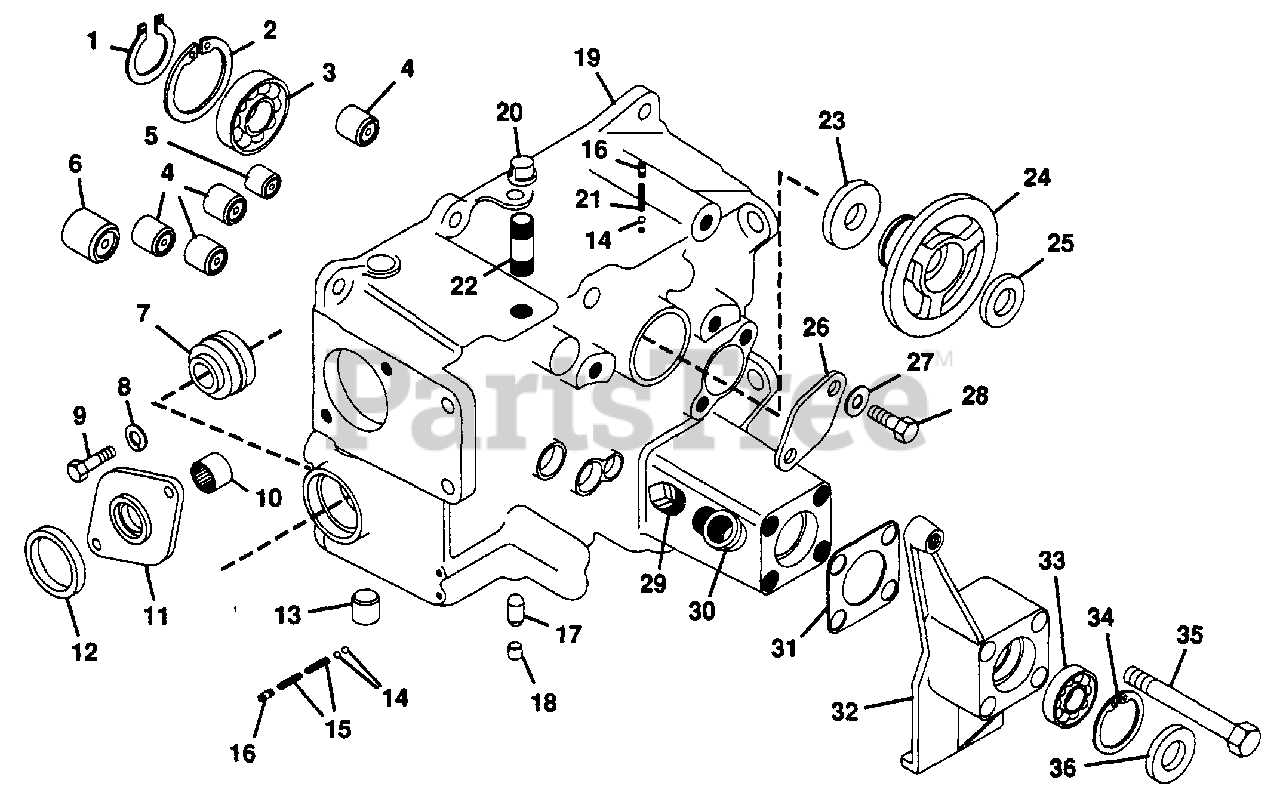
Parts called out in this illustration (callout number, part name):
1	RING, RETAINING 1.969 SHAFT
2	RING, RETAINING 3.156 BORE
3	BEARING, BALL 1.968X3.149X.629
4	BEARING, NEEDLE .75X1X.75
5	BEARING, NEEDLE .625X.812X.750
6	BRG, NEEDLE 1.000X1.250X.750
7	ASM, BEARING 1.000X1.980X1.243
8	WASHER, LOCK 5/16 REG.
9	BOLT, HEX 5/16-18X1.00
10	BEARING
11	CAP, FRONT PTO
12	SEAL, OIL .750X1.254X.188
13	PLUG
14	BALL, STEEL 5/16
15	SPRING, COMP. 1.50X.30X26 LB/IN
16	PLUG, PIPE 1/8
17	PIN, INTERLOCK
18	PLUG, CUP 3/8
19	ASSEMBLY, TRANSMISSION CASE(INCLUDES ITEM NUMBERS 4 THROUGH 7.)
20	CAP, PIPE 1/2 NPT
21	SPRING
22	NIPPLE, PIPE 1/2X2.5
23	SEAL, OIL 2.250X3.005X.375
24	HUB, CLUTCH
25	SEAL, OIL .75X1.625X.25
26	PLATE, COVER
27	WASHER, FLAT .406X.812X.065
28	BOLT, HEX 3/8-16X.750
29	PLUG, PIPE 1/2
30	ELBOW, 1/2 90 DEGREE STREET
31	GASKET(SERVICE ONLY)
32	RETAINER, AXLE BEARING
33	BEARING, BALL SEALED
34	RING, RETAINING
35	BOLT, HEX 1/2-13X3.25
36	SEAL, OIL AXLE
